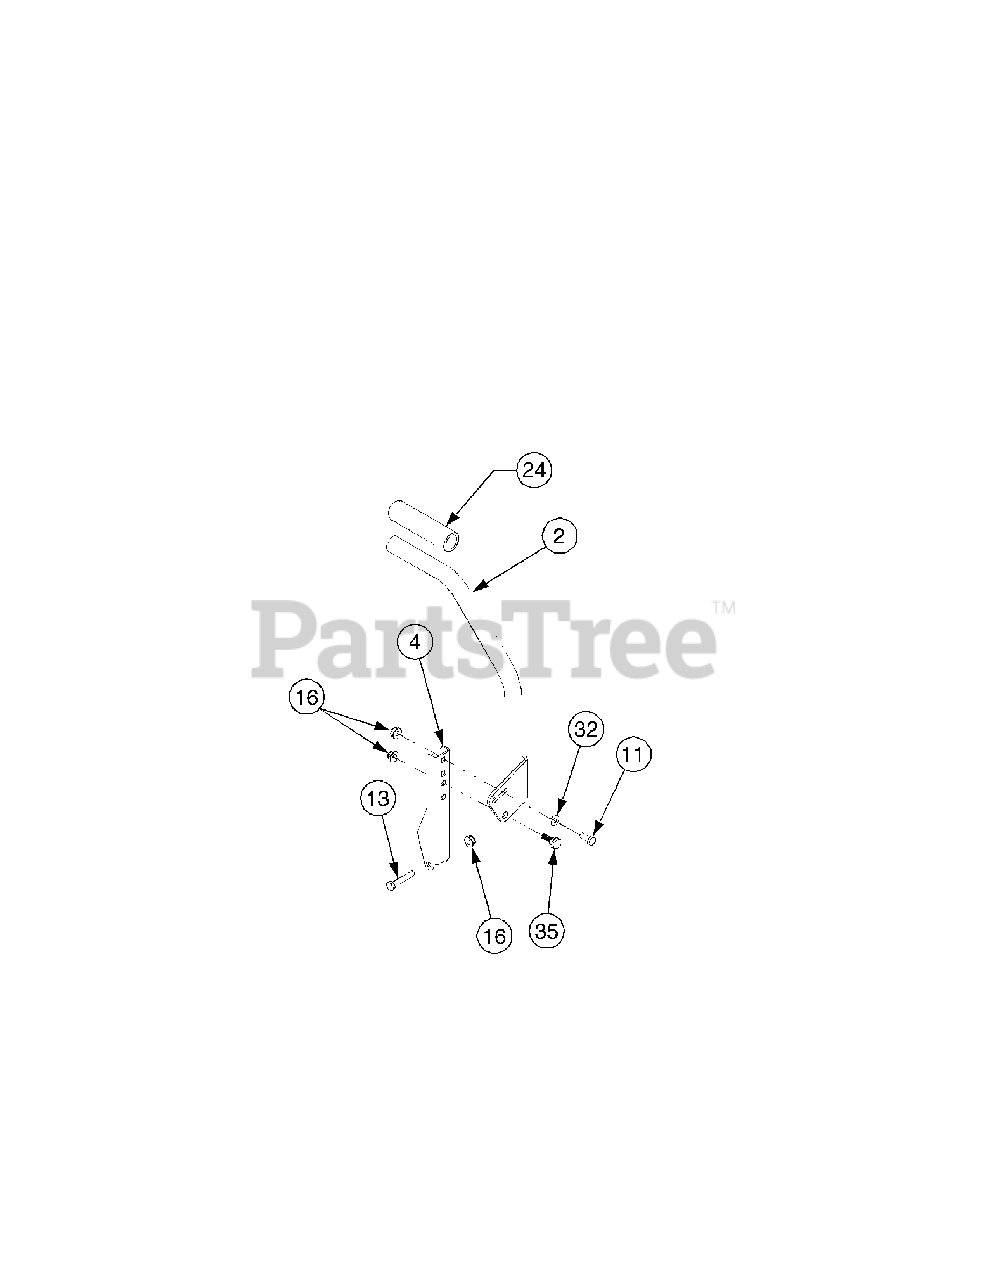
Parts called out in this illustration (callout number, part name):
4	Bracket, Lapbar Pivot
11	Screw, Hex Cap, 5/16-18 x .75 GR5
13	Screw, Hex Cap, 5/16-18 x 1.75 GR5
16	Nut, Hx Flange Insert Lck, 5/16-18 GrF
24	Grip, Hand
32	Washer, Flat, .344 x .688 x .065
35	Screw, Shoulder, .437 x .268:5/16-18
